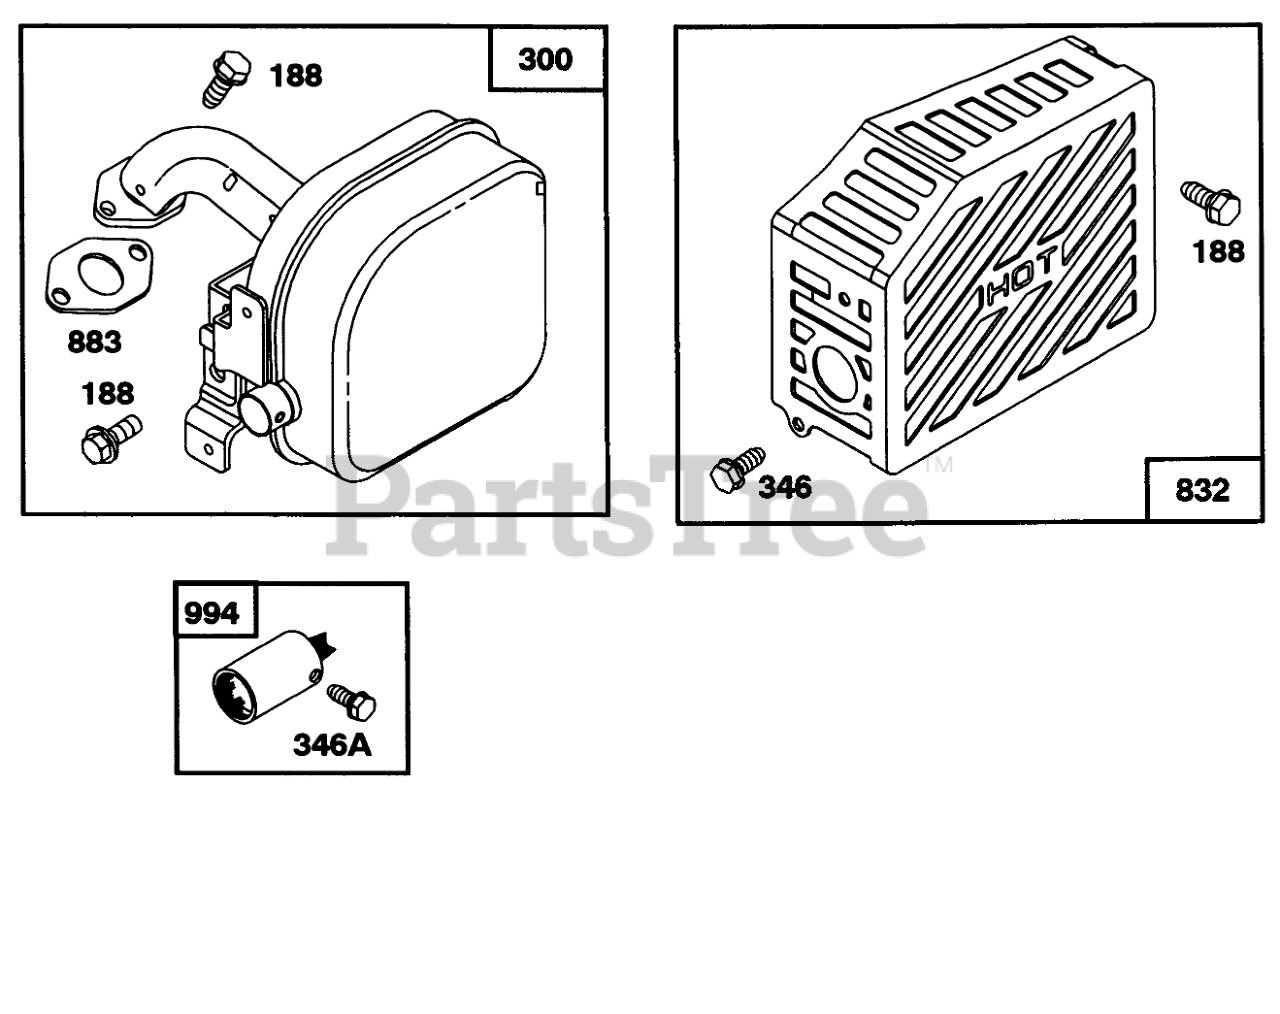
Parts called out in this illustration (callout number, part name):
188	SCREW - SEM
300	MUFFLER - EXHAUST
346	SCREW - SELF-TAPPING
346A	SCREW - ARRESTER MTG.
832	OIL FILLER TUBE
883	EXHAUST GASKET
977	CARBURATOR GASKET SET
994	ARRESTER - SPARK
